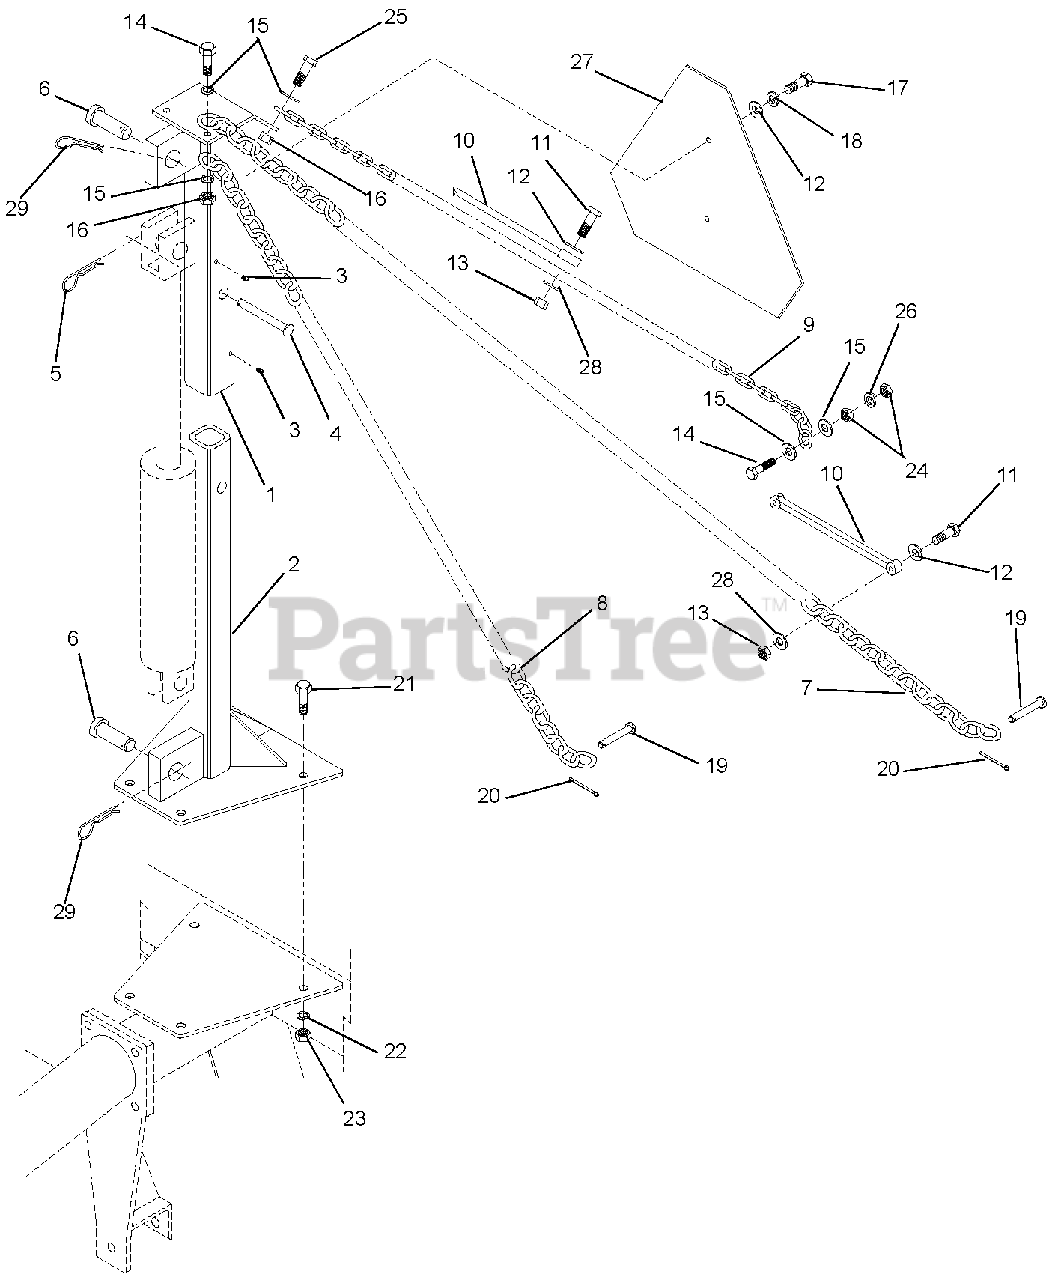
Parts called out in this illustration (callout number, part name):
1	Weldment, Outer Lift Tube
2	Weldment, Inner Lift Post
3	Fitting, Grease .187 Drive
4	Pin, Clevis .625 x 4
5	Pin, Presto Spring Clip
6	Pin, Clevis 1 x 2.25
7	Chain, Outer Front Lift
8	Chain, Inner Front Lift
9	Chain, Rear Lift
10	Strap, Tarp 8.25-Inch No Hook
11	Bolt, Hex .25-20 x 1.50
12	Washer, Flat .25
13	Nut, Hex .25-20 CP Nylock
14	Cap Screw, Hex Head .375-16 x 1.5
15	Washer, Flat 3/8 USS
16	Nut, Hex, Nyloc .375-16 CP
17	Cap Screw, Hex Head 1/4-20
18	Washer, Lock 1/4 CP
19	Pin, Clevis .375 x 1.5
20	Pin, Cotter .156 x 1
21	Cap Screw, Hex Head .50-13 x 1.5
22	Washer, Lock, .50 CP
23	Nut, Hex .50 CP
24	Nut, Jam .375-16
25	Cap Screw, Hex Head .375-16 x 1.0
26	Washer, Lock .375 CP
27	Sign, Slow-Moving Vehicle
28	Washer, Flat .25 x 1.0
29	Pin, Cotter .125
